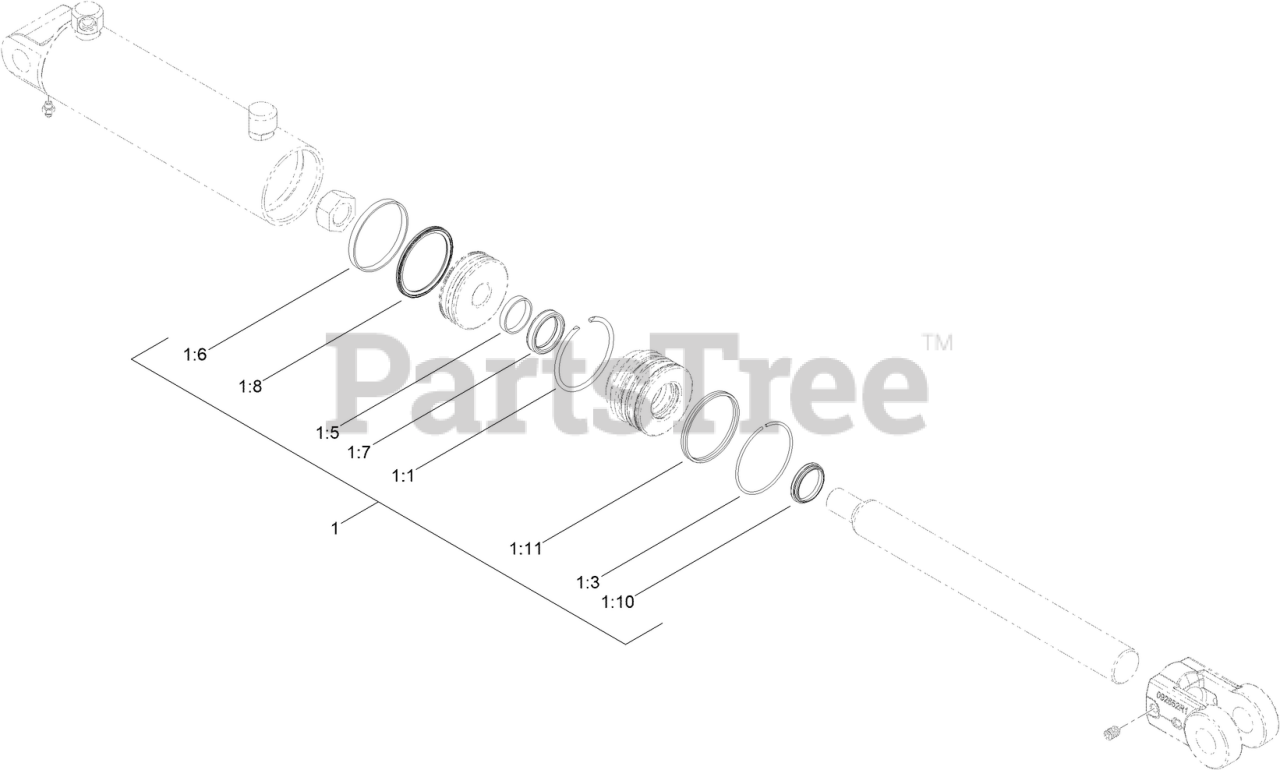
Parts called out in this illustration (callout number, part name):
1	KIT-SEAL, HYDRAULIC CYL
1:12	SEAL KIT STUFF WIRE RNG REP
1:13	SEAL KIT STUFF TSS SEALS
